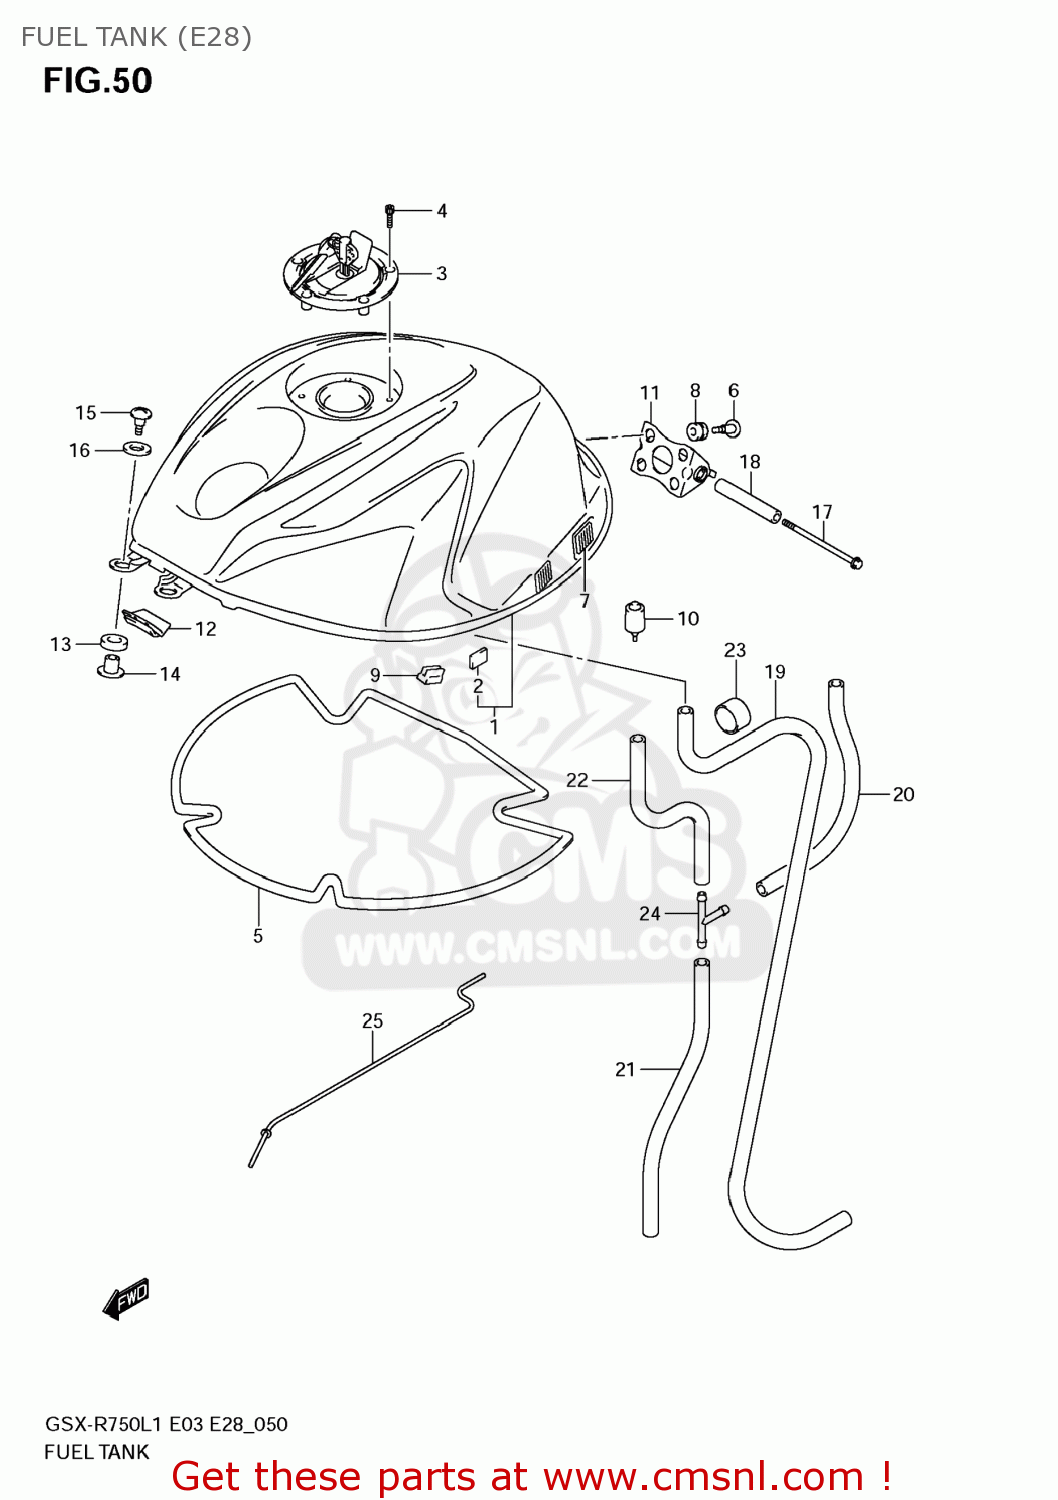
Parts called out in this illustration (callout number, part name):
1	TANK ASSY,FUEL
2	FASTENER,FUEL TANK COVER
3	CAP SET,FUEL TANK
4	BOLT(5X20)
5	SHIELD,FUEL TANK HEAT
6	SCREW,FUEL TANK RR BRACKET
7	FASTENER
8	CUSHION
9	CUSHION,FUEL TANK COVER
10	CUSHION,FUEL TANK RR
11	BRACKET,FUEL TANK NO.1
12	RUBBER,FUEL TANK FR
13	CUSHION,FUEL TANK FR
14	SPACER,FUEL TANK FR
15	SCREW(6X25)
16	WASHER(6.5X22X1.6)
17	BOLT(6X110)
18	SPACER,FUEL TANK RR
19	HOSE,FUEL TANK WATER DRAIN
20	HOSE,FUEL TANK BREATHER NO.1
21	HOSE,FUEL TANK BREATHER NO.2
22	HOSE,VACUUM
23	HOSE(12X16X600)
24	3 WAY
25	STAY,FUEL TANK
